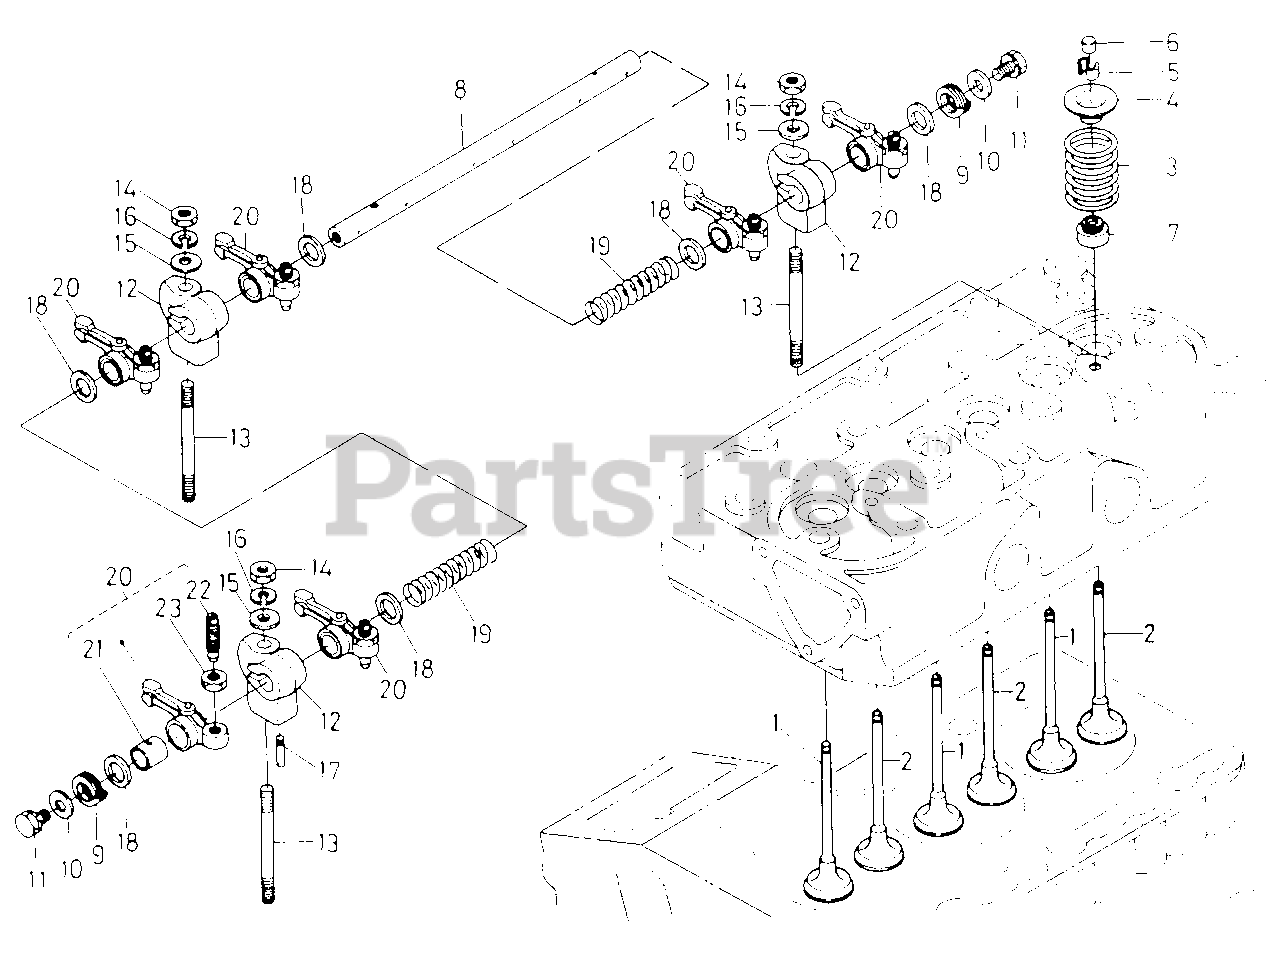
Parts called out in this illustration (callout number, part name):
2	Valve, Exhaust
3	Spring, Valve
4	Retainer, Valve Spring
5	Collar, Valve Spring
7	Seal, Valve Stem
8	Shaft, Rocker Arm
10	Washer, Plain
11	Bolt, M6 X 10 Class 8.8
12	Support, Rocker Arm
14	Nut, M6 Znd Class 8
16	Washer, 6MM Lock
17	Screw, Rocker Arm Shaft
18	Washer, Rocker Arm Shaft
19	Spring, Rocker Arm
20	Arm Assy, Rocker
22	Screw, Adjusting
